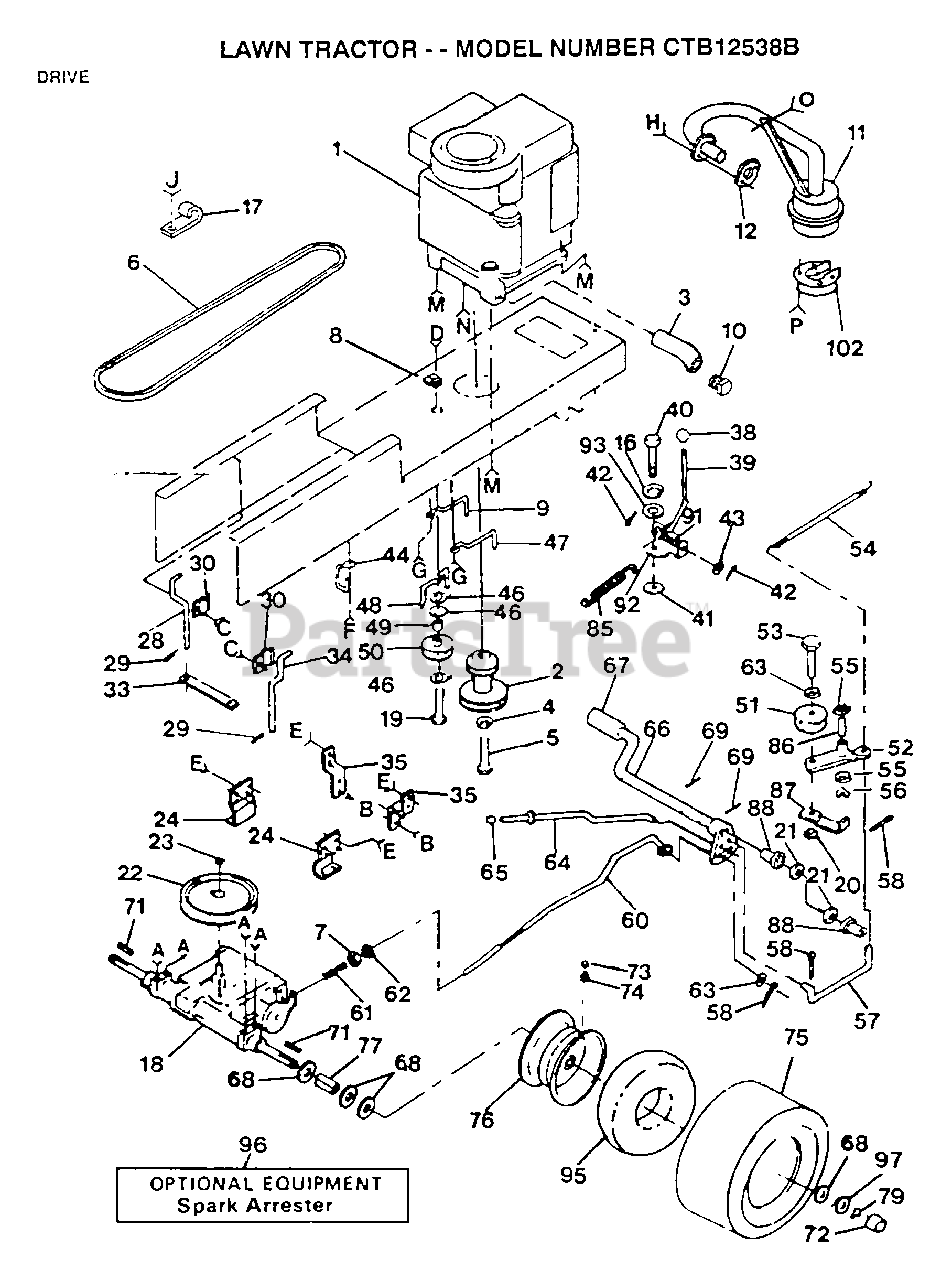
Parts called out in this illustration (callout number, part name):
4	LOCKWASHER
5	BOLT
6	BELT-V.90.0.GD.DR
7	NUT
8	CLIP T
9	KEEPER BELT ENGLH
11	MUFFLER
16	LOCKWASHER
17	INSUL CLIP T
19	BOLT
21	WASHER LT
22	PULLEY TRANS
24	BRACKET LT
28	KEEPER BELT LH
29	SPRING.RETAINER
30	CLAMP LT
33	STRAP LOCATOR
34	KEEPER BELTRH
35	STRAP TORQUE
38	CONTROL KNOB LT
39	ROD SHIFTER
41	WASH-SHFT PLT LT
42	PIN COTTER 1/8
43	WASHER
46	WASHER
47	"KEEPER,BLT ENG LT"
48	BELT KEEPER LT
49	SPACER T
50	PULLEY.IDLER.FLAT
52	ARM IDLER
54	"SPRING, RETURN LT"
55	WASHER LT
56	KLIP RING
57	"LINK, CLUTCH T"
58	COTTER PIN
60	BRAKE ROD LT
61	SPRING ROD LT
62	NUT
63	WASHER
67	PEDAL COVER T
68	WASHER
71	SQUARE KEY
72	HUB CAP
73	VALVE CAP
74	VALVE STEM LT
77	SPACER LT
79	E-RING LT
86	"LY, BEARING"
87	RETAIN BELT
88	NYLON BEARING
91	SPRING LT
92	PLATE SHIFT LT
93	WASHER LT
95	TUBE.18X9.5-8
97	WASHER
102	DEFLECTOR.222573
